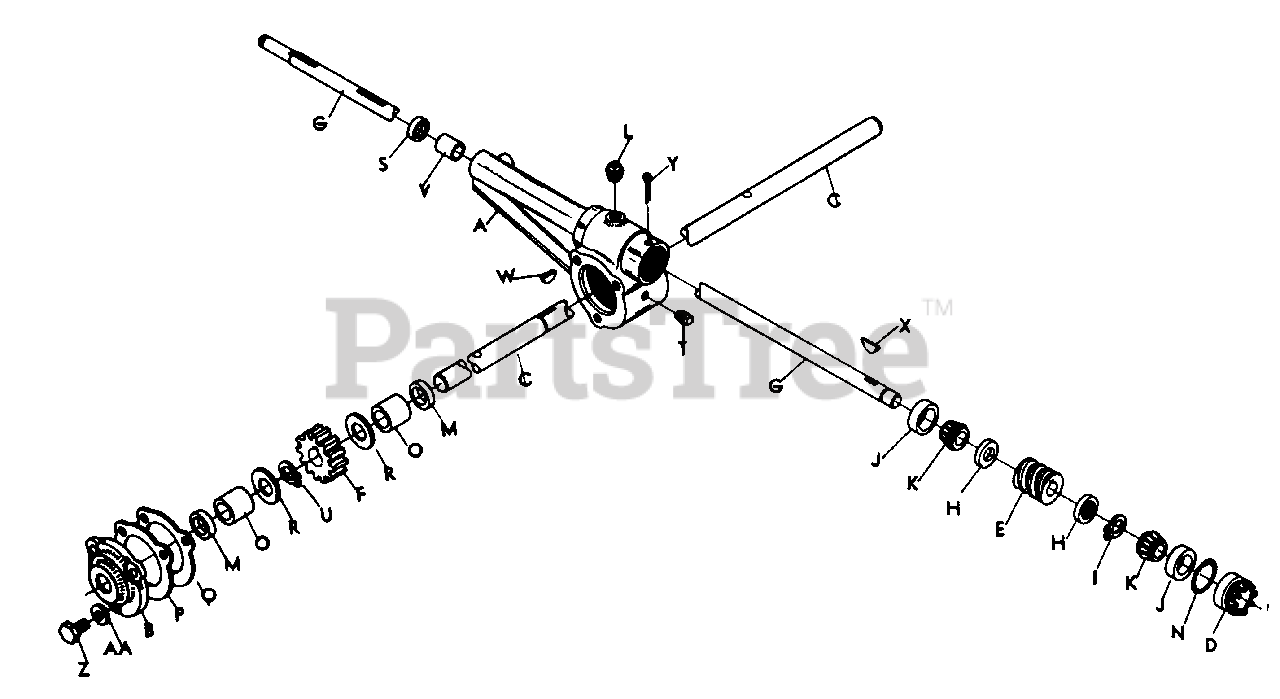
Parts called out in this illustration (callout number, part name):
A	Gear Case
B	Gear Case Cover
C	Output Shaft
D	Adjustment Plug
E	Worm
F	Worm Wheel
G	Input Shaft
H	Spacer
I	Retaining Ring
J	Bearing Cup
K	Bearing Cone
L	Vent Plug Assembly
M	Seal
N	O-Ring
O	Bearing
P	Gasket
Q	Gasket
R	Washer
S	Seal
T	Pipe Plug
U	Retaining Ring
V	Bearing
W	1/4 x 7/8 Woodruff Key-Alloy H.T.
X	3/16 x 5/8 Hypro Key
Y	1/8 x 3/4 Cotter Pin-Pl.
Z	5/16-18 x 1 Hex Hd. Capscrew-Pl.
AA	5/16 Lockwasher-Pl.
